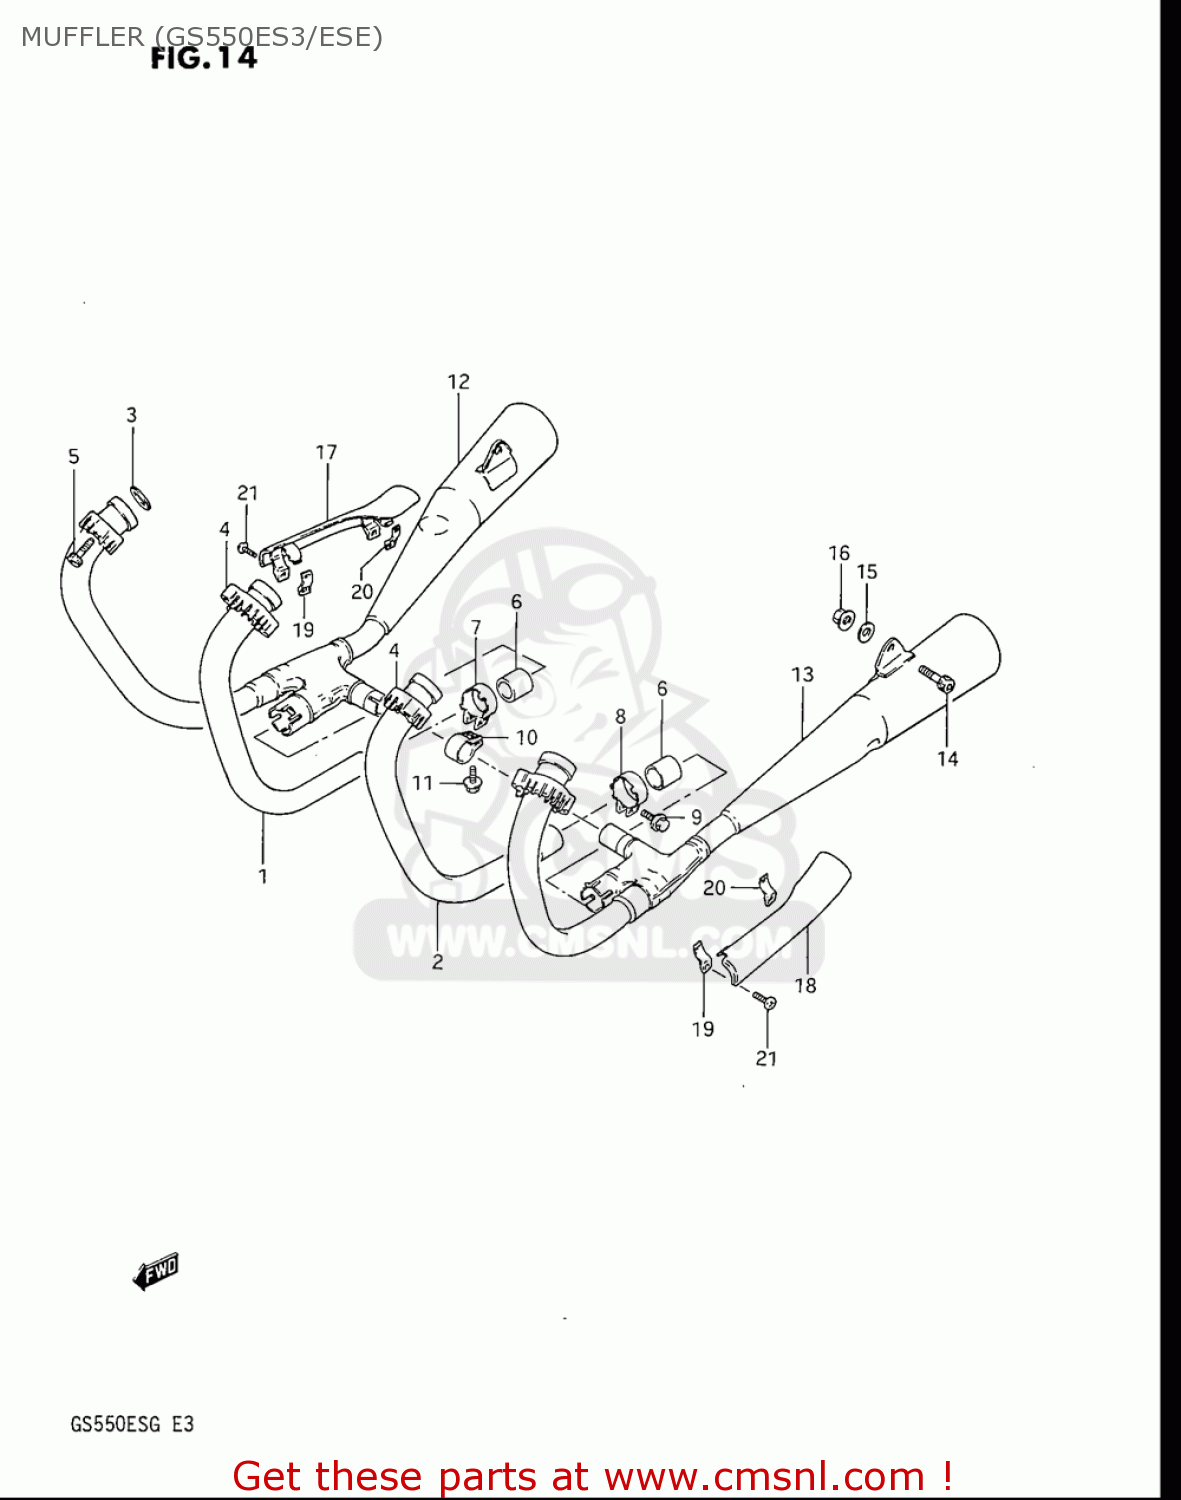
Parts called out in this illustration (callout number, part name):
3	GASKET,EXHAUST (NAS)
4	CLAMP,EXHAUST PIPE
5	BOLT
6	CONNECTOR,MUFFLER
7	CLAMP,MUFFLER CONNECTOR,R
8	CLAMP,MUFFLER CONNECTOR,L
9	BOLT
11	BOLT
14	BOLT
15	WASHER(10.5X20X3.2)
16	NUT (M10X1.25X9)
20	CLAMP,MUFFLER COVER
21	SCREW
